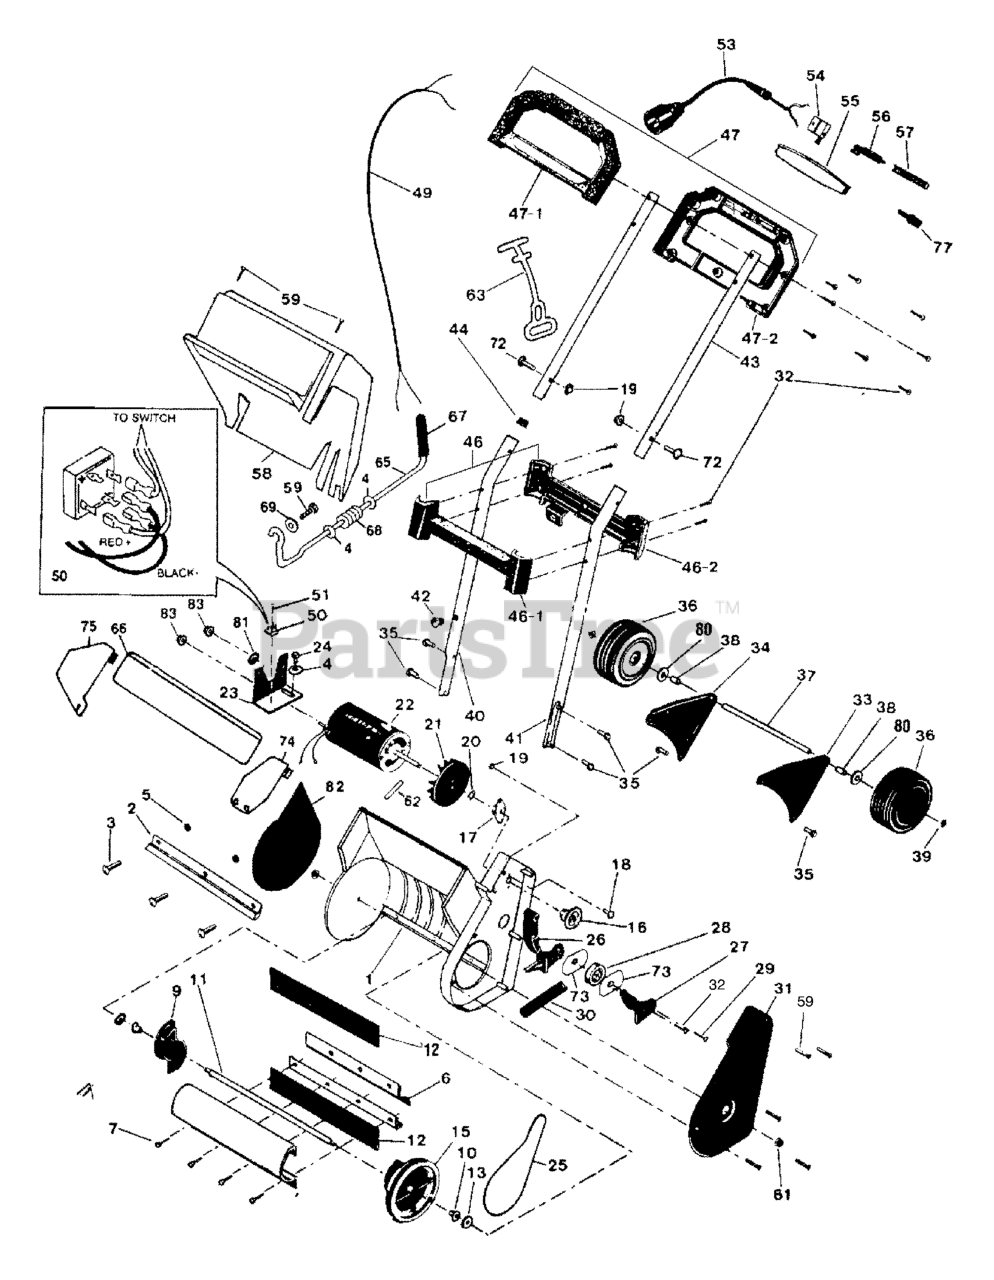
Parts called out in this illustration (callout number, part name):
1	Housing, Scoop
2	Blade, Scraper
4	Washer, Flat
5	Nut, 1/4-20
6	Segment, Drum
9	Cap, Drum End
10	Bearing, Bronze
11	Shaft, Paddle
12	Paddle, Auger
13	Washer, Flat
15	Pulley, Driven
16	Pulley, Drive
17	Bearing, Self Align
18	Screw, 1/4-20
19	Nut, 1/4-20
20	Ring, Retainer
21	Fan, Motor
22	Motor, 120V
23	Bracket, Motor Mount
24	Screw, 1/4-14x0.75
25	Belt, Drive
26	Arm, Idler
27	Bearing, Retainer Idler
28	Bearing, Ball
30	Spring Idler
31	Cover, Left Drive Housing
33	Bracket, Left Wheel
34	Bracket, Right Wheel
35	Screw
36	Wheel, 15"
38	Spacer, Wheel
39	Nut, Push On Cap
40	Handle, Right Lower
41	Handle, Left Lower
42	Bushing
43	Handle, Upper
44	Protector, Harness
45	Harness, Protector
46	Set, Handle Assist
46-1	Order Set
46-2	Order Set
47	Set, Handle Grip
47-1	Order Set
47-2	Order Set
49	Harness, Wire
50	Rectifier, Full Wave
53	Connecting Lead
54	Switch
55	Bar, Switch
56	Lever, Switch
57	Spring, Switch
58	Cover, Motor
62	Pin, Grooved
63	Strain Relief, Cord
65	Rod, Discharge
66	Slider, Vane
67	Grip, Hand Vinyl
68	Spring, Actuator Rod
69	Washer, Flat
73	Retainer, Belt
74	Deflector, Outer
75	Deflector, Inner
77	Key, Hi-Pro
80	Washer, Flat
81	Grommet
82	Cover, Right Housing
